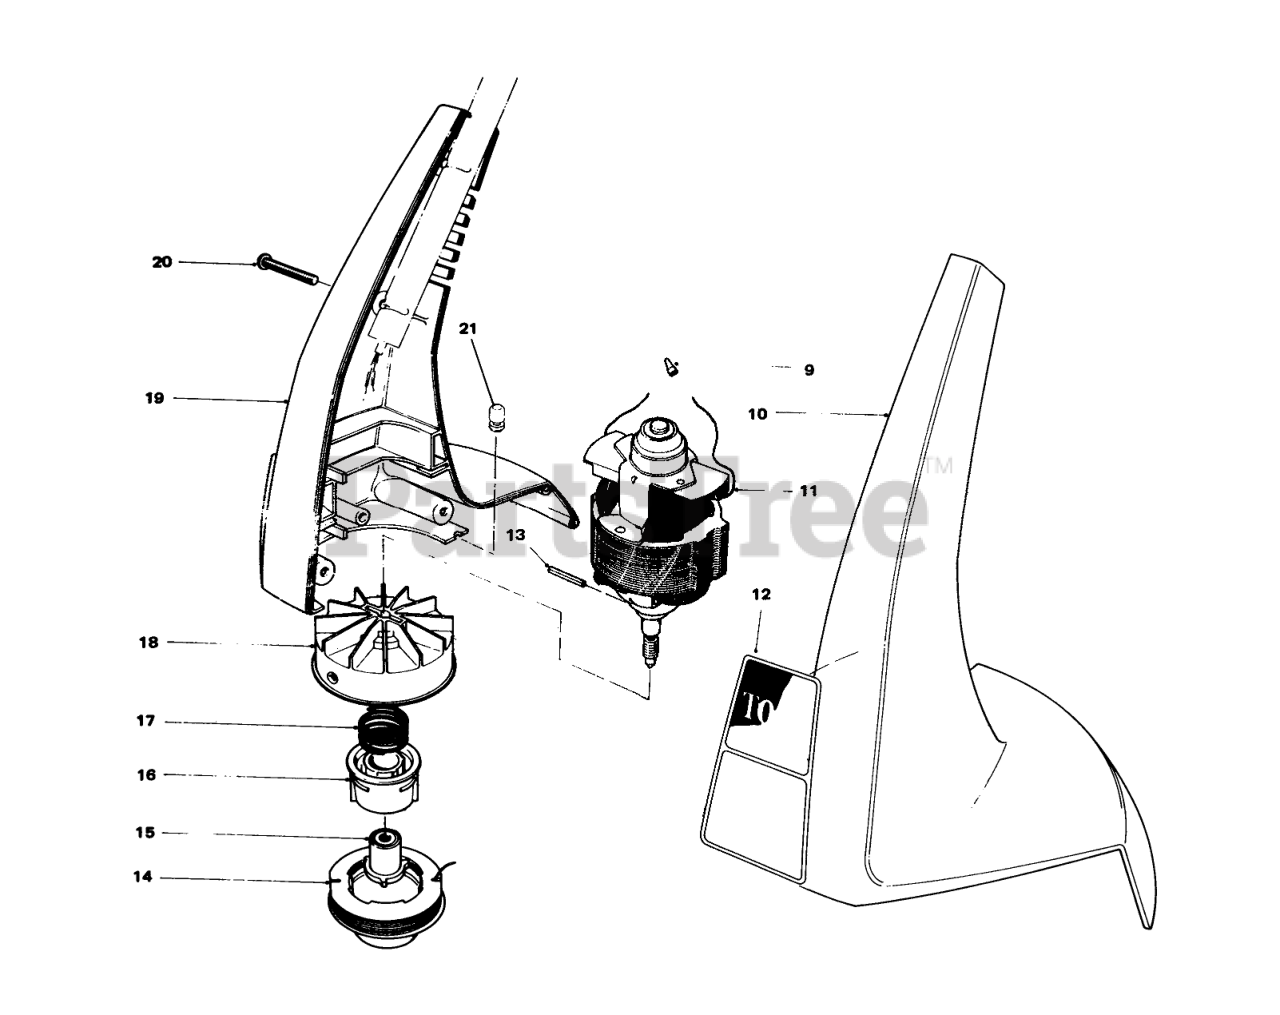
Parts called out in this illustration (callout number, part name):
9	CONNECTOR WIRE JOINT
10	Housing L.H.
11	Motor
12	DECAL 900
13	COIL PIN
14	Prewound Spool
15	Driver
16	CORE - SPOOL
17	SPRING-COMPRESSION
18	FAN HUB ASM
19	Housing R.H.
20	Screw
21	GROMMET
